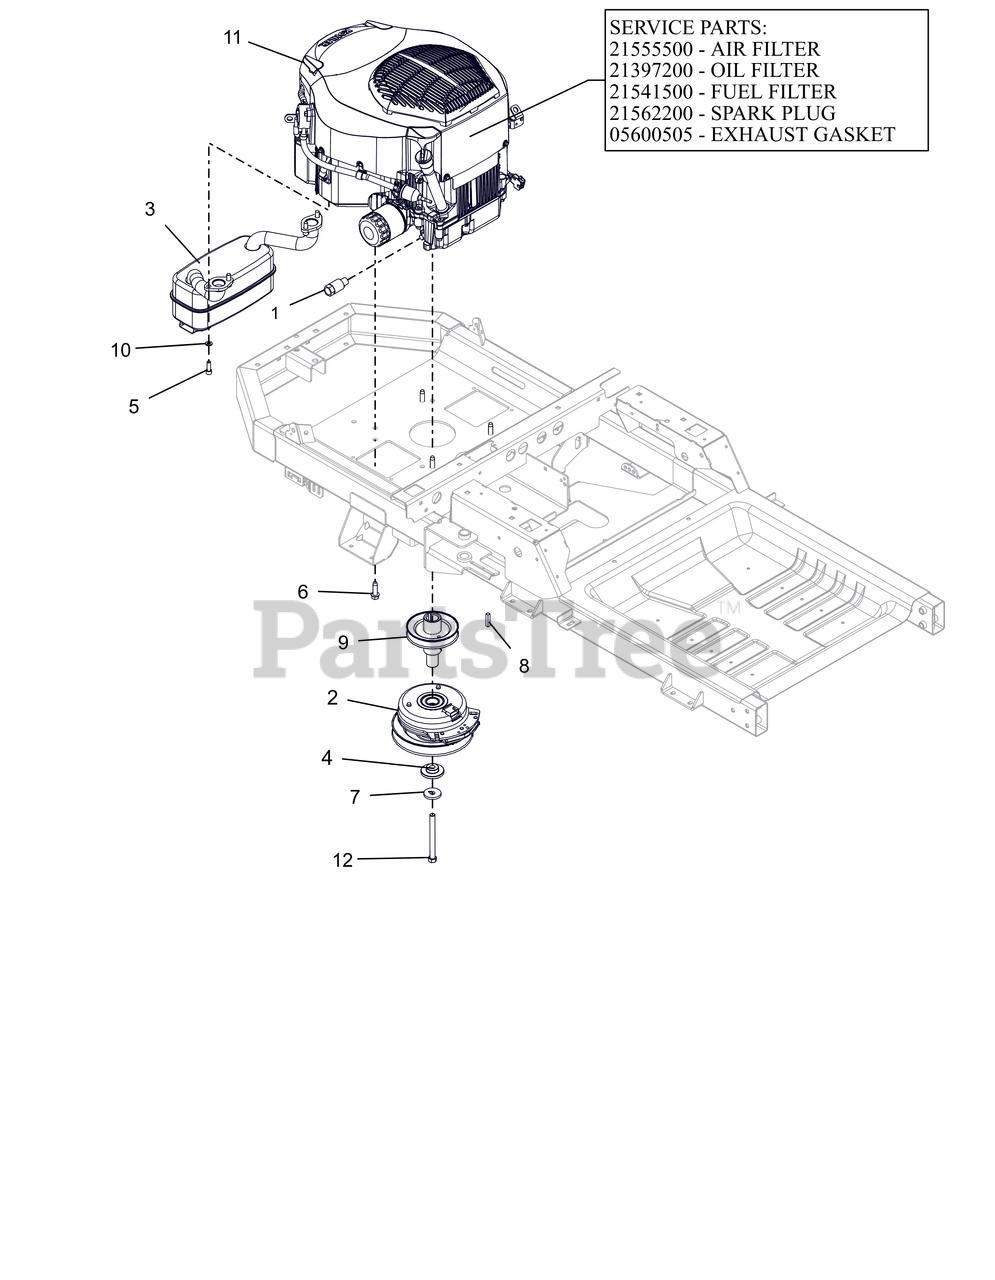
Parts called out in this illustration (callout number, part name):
1	DRAIN, OIL
2	CLUTCH,105FTLB MONOPOLE 6.83"
3	MUFFLER - KOHLER
4	BSHG-FLG .469X1.06X.574X2.0
5	SCR-CAP .31-18X.88 S/HD G8 ZCC
6	SCR,TAP .375-16X1.25HWH TR ZCC
7	WASHER, 7/16" SPRING DISK
8	KEY-SQ .25 X 1.25 X .25 SAE
9	WLDMT, DRIVE SHEAVE-X
10	WSHR,LK-REG .312X.078 ZCC
11	ENGINE, KOHLER 22HP TWIN
11	AIR CLEANER, KOHLER
11	FILTER, OIL - KOH CV20
11	FILTER, FUEL
11	PLUG, SPARK (RFI)
11	GASKET, MUFFLER COURAGE TWIN
12	BLT, HEX .44-20X4.50 G8 ZCC NT
